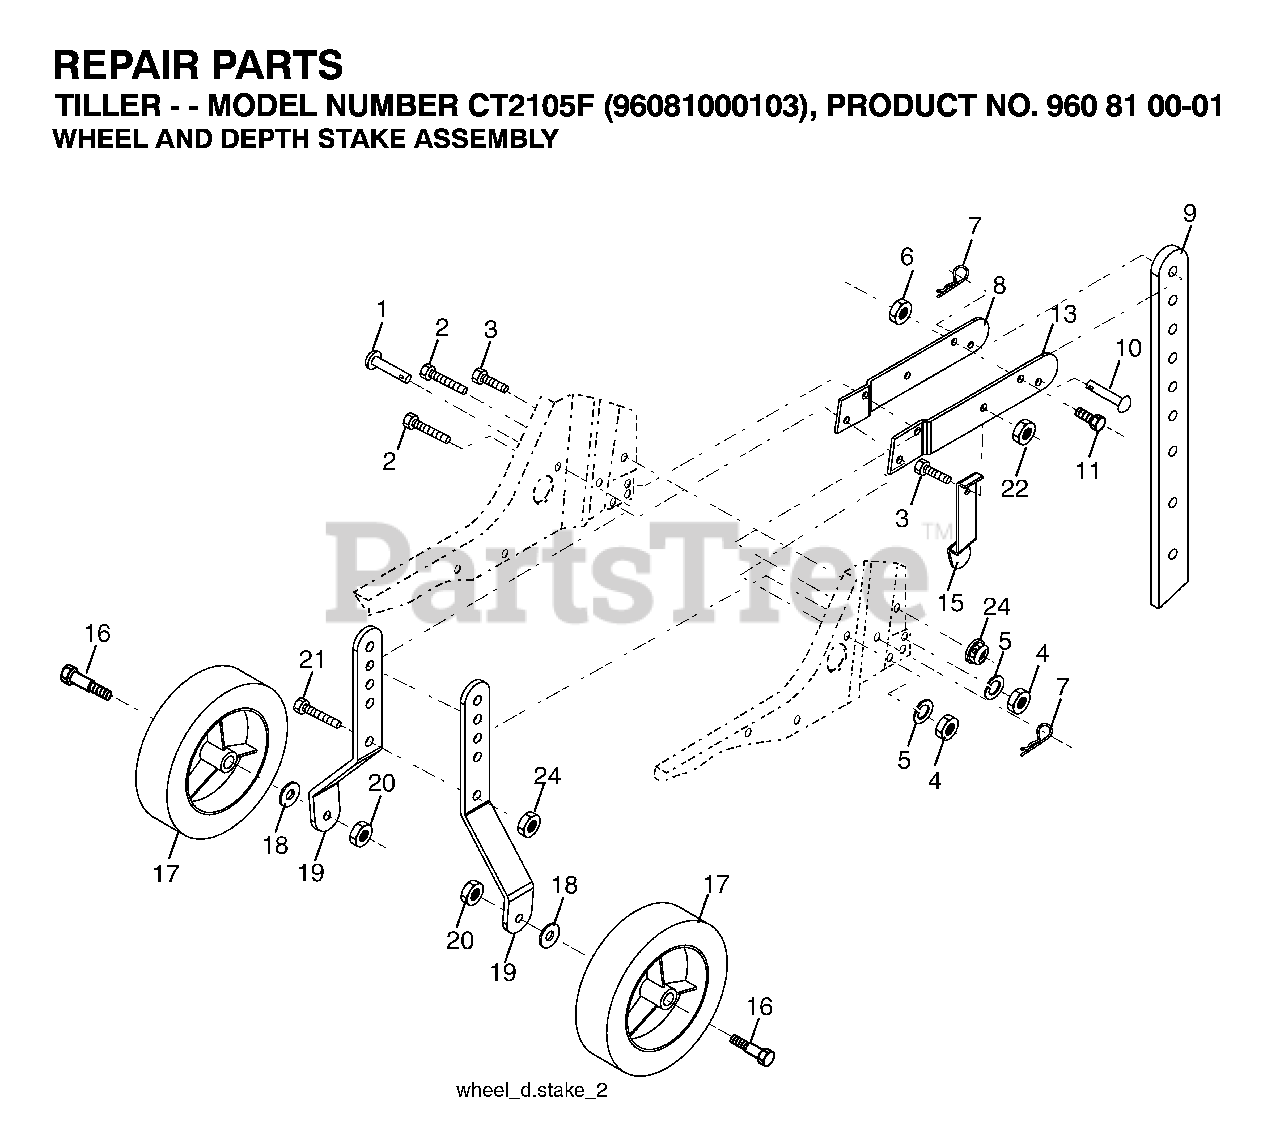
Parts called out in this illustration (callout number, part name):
1	PIN
2	BOLT
3	BOLT
5	LOCKWASHER
6	NUT
7	SPRING TI
8	SUPPORT.STAKE.RH.BLACK
9	RP STAKE.DEPTH.13.25.W/9HOLES
11	BOLT
16	BOLT.SHOULDER
18	WASHER
20	LOCKNUT
21	BOLT RB
22	NUT.71038.31-18.HEX.NYLOCK
24	LOCKNUT-FLANGE 5/16-18
